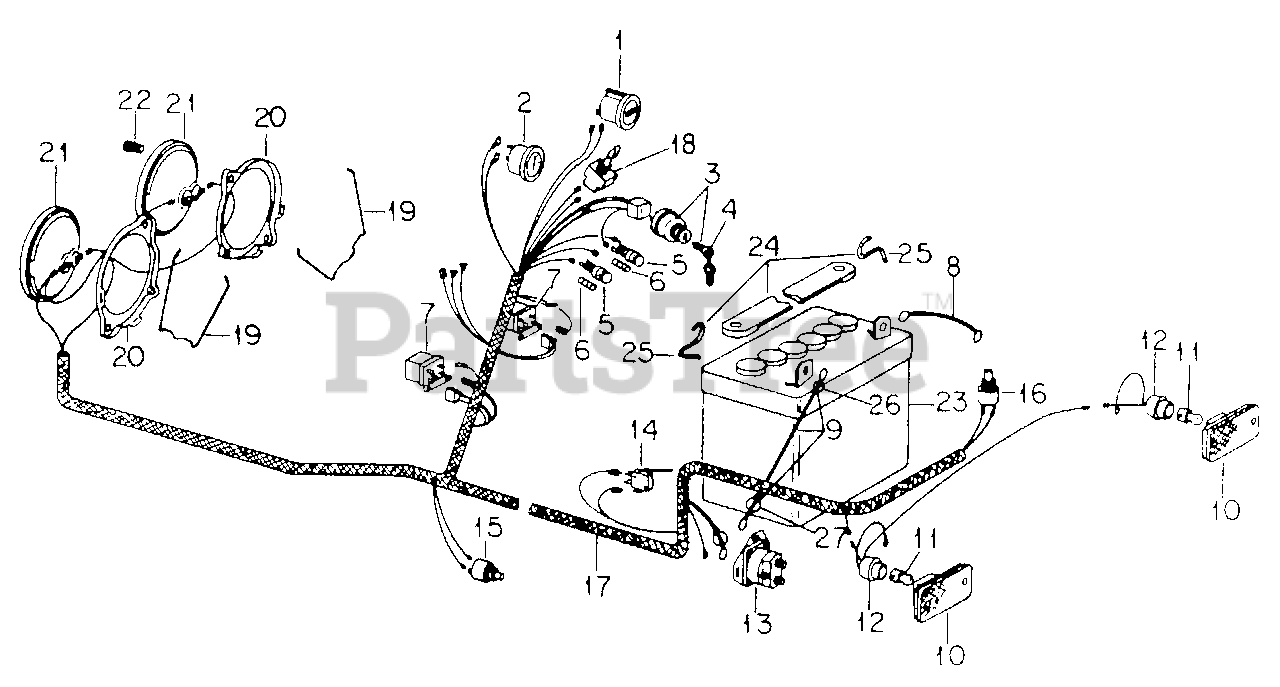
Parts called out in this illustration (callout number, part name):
1	Package, Hourmeter
2	Indicator, Charge
3	Switch, Magneto Ignition
4	Key, Ignition Switch
5	Holder, Fuse
6	Fuse, 15 Amp
7	Relay
8	Cable, Battery Negative Terminal to Ground
9	Cable, Battery, Positive
10	Lens Assy, Taillight
11	Bulb, Taillight #194
12	Cable Assy, Taillight
13	Switch, Magnetic, Solenoid
14	Switch, Reverse Cut Out
15	Switch, Neutral Start
16	Switch, Neutral Start
17	Harness Assy, Main Cable
18	Switch, PTO
19	Spring, Headlamp Retaining
20	Retainer, Headlamp
21	Light, Sealed Beam Head
22	Screw, Headlight
23	Battery, 12 Volt
24	Strap Assy, Battery
25	Hook, Battery Strap
26	Cover, Battery Terminal
27	Insulator, Terminal Boot
